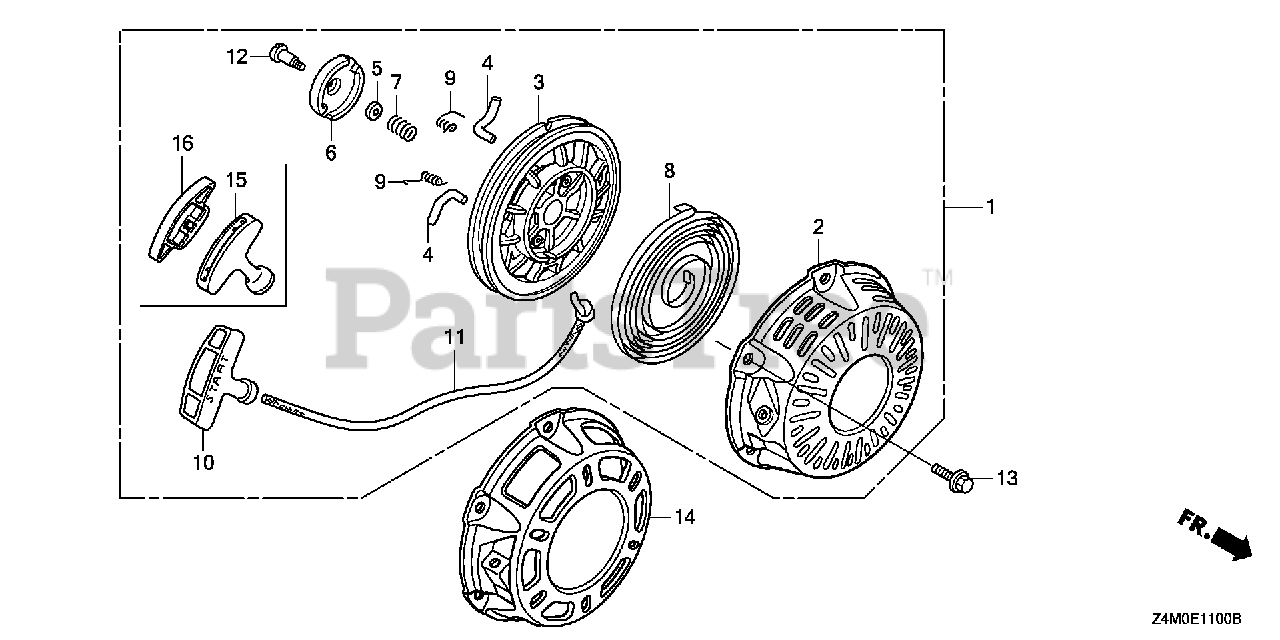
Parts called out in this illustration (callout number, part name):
1	STARTER ASSY., RECOIL *R280* (COO)(FOR U.S.A.) (POWER RED)
2	CASE, RECOIL STARTER *R280* (POWER RED)
3	REEL, RECOIL STARTER
4	RATCHET, STARTER
5	PLATE, FRICTION
6	GUIDE, RATCHET
7	SPRING, FRICTION
8	SPRING, RECOIL STARTER
9	SPRING, RETURN
11	ROPE, RECOIL STARTER
12	SCREW, SETTING
13	BOLT, FLANGE (6X10)
15	KNOB, RECOIL STARTER (COO)(FOR U.S.A.)
16	KNOB, REINFORCEMENT
